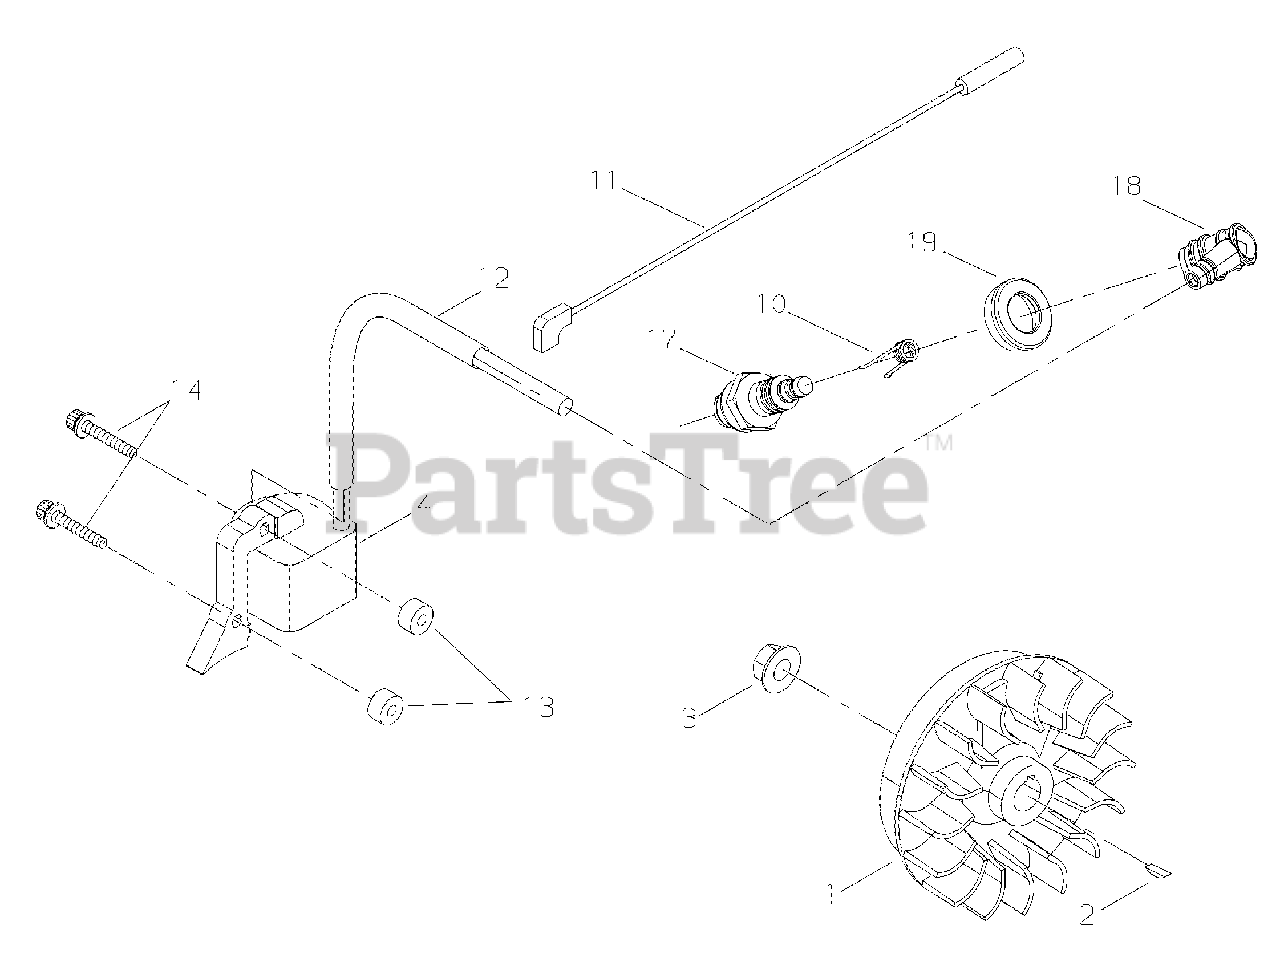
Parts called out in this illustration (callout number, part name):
1	FLYWHEEL
2	KEY, WOODRUFF 3×10
3	NUT M8
4	COIL, IGNITION
10	TERMINAL, SPARK PLUG
11	LEAD - IGNITION L= 215
12	TUBE, IGNITION COIL
13	INSULATOR 4.2×11×6
14	BOLT, ADHESIVE M4×20
17	SPARK PLUG - BPMR6A
18	CAP, SPARK PLUG
19	SEAL, SPARK PLUG
